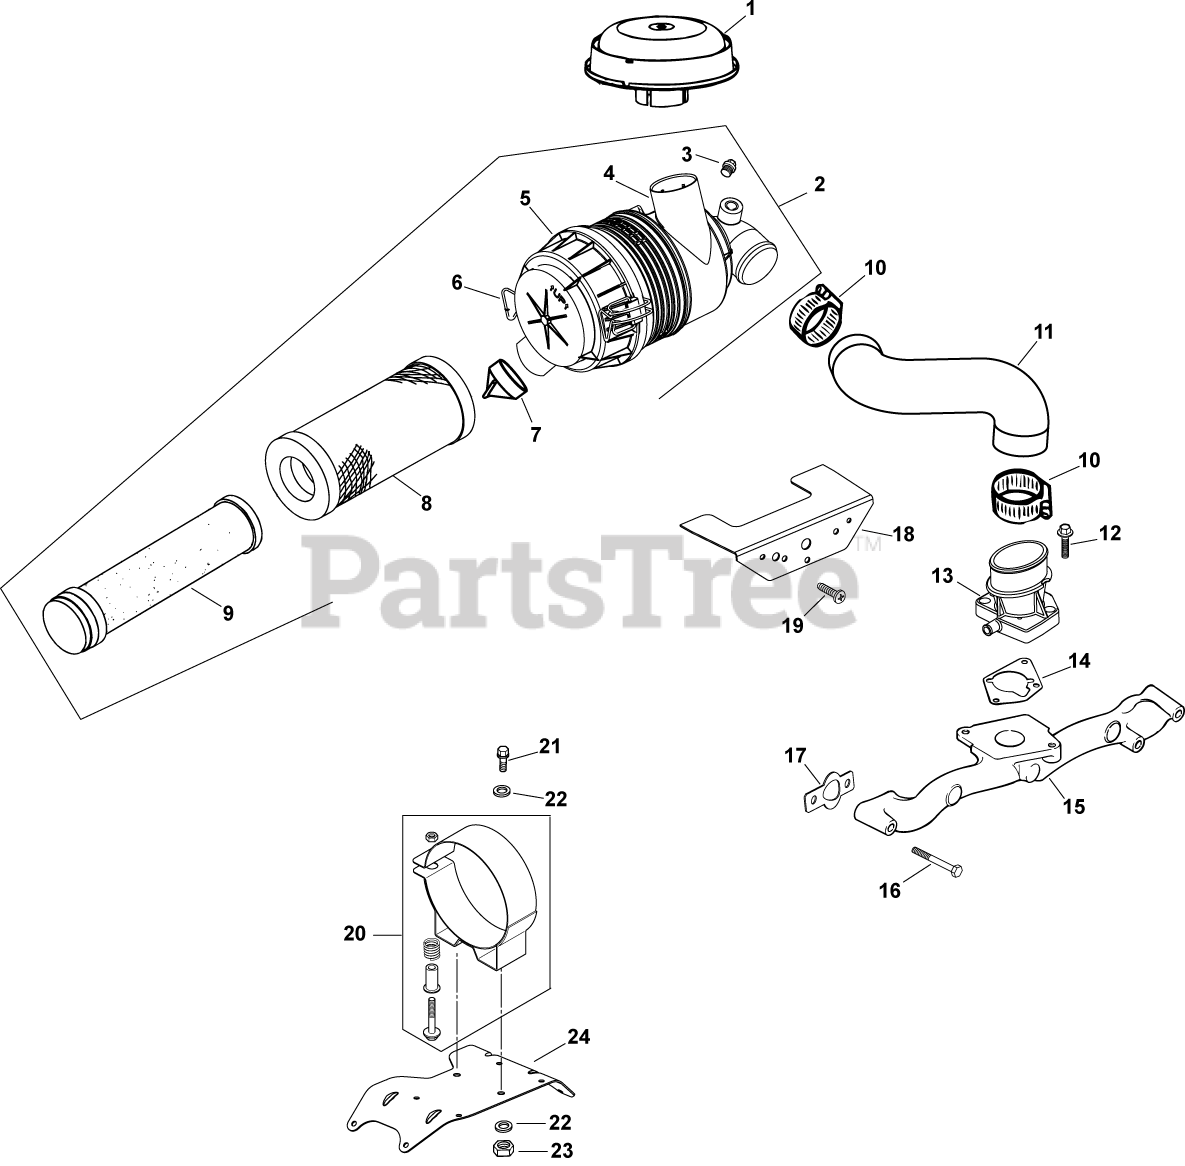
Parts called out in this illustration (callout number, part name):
1	HOOD, INLET
2	AIR CLNR, CANISTER-USE 25 048 17-S
3	PLUG, PIPE
4	HOUSING, HD AIR CLEANER
5	COVER ASSEMBLY, AIR CLEANER
6	CLIP - USE 62 154 07-S
7	VALVE, DUST EJECTOR
8	ELEMENT, AIR FILTER - PRIMARY
9	ELEMENT, AIR FILTER - SAFETY
10	CLAMP, HOSE-USE 25 237 21-S
11	HOSE, AIR CLEANER
12	SCREW, FLG M6X1.0X25
13	KIT, REMOTE AIR CLEANER ADAPTER
14	GASKET, AIR CLEANER BASE
15	MANIFOLD, METAL INTAKE
16	SCREW, FLG M6X1.0X55
17	GASKET, INTAKE MANIFOLD USE 24 041 79-S
18	SHIELD, DEBRIS
19	SCREW, PHL HD 11-16X3/4"
20	BRACKET, AIR CLEANER
21	SCREW, FLG M6X1.0X16
22	WASHER, FLAT 1/4"
23	NUT, LOCK M6X1.0
24	BRACKET, AIR CLEANER
